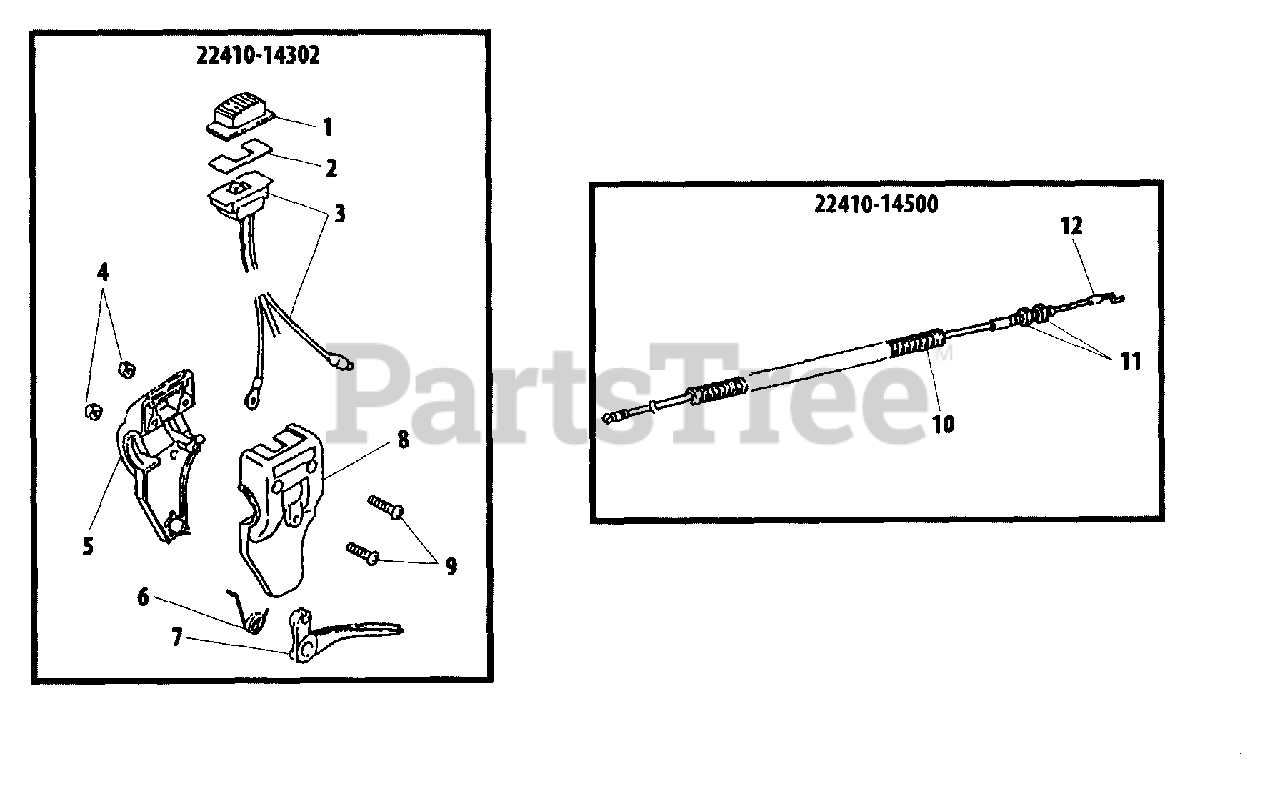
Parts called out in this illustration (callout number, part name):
1	KNOB
2	PLATE, SWITCH
3	SWITCH
4	NUT - 5
5	BRACKET - RIGHT
6	SPRING, TRIGGER
7	TRIGGER, THROTTLE
8	BRACKET - LEFT
9	SCREW - 5X20
10	TUBE
11	NUT - 6
12	CABLE, THROTTLE
22410-14302	THROTTLE CONTROL KIT
22410-14500	THROTTLE CABLE ASSY
